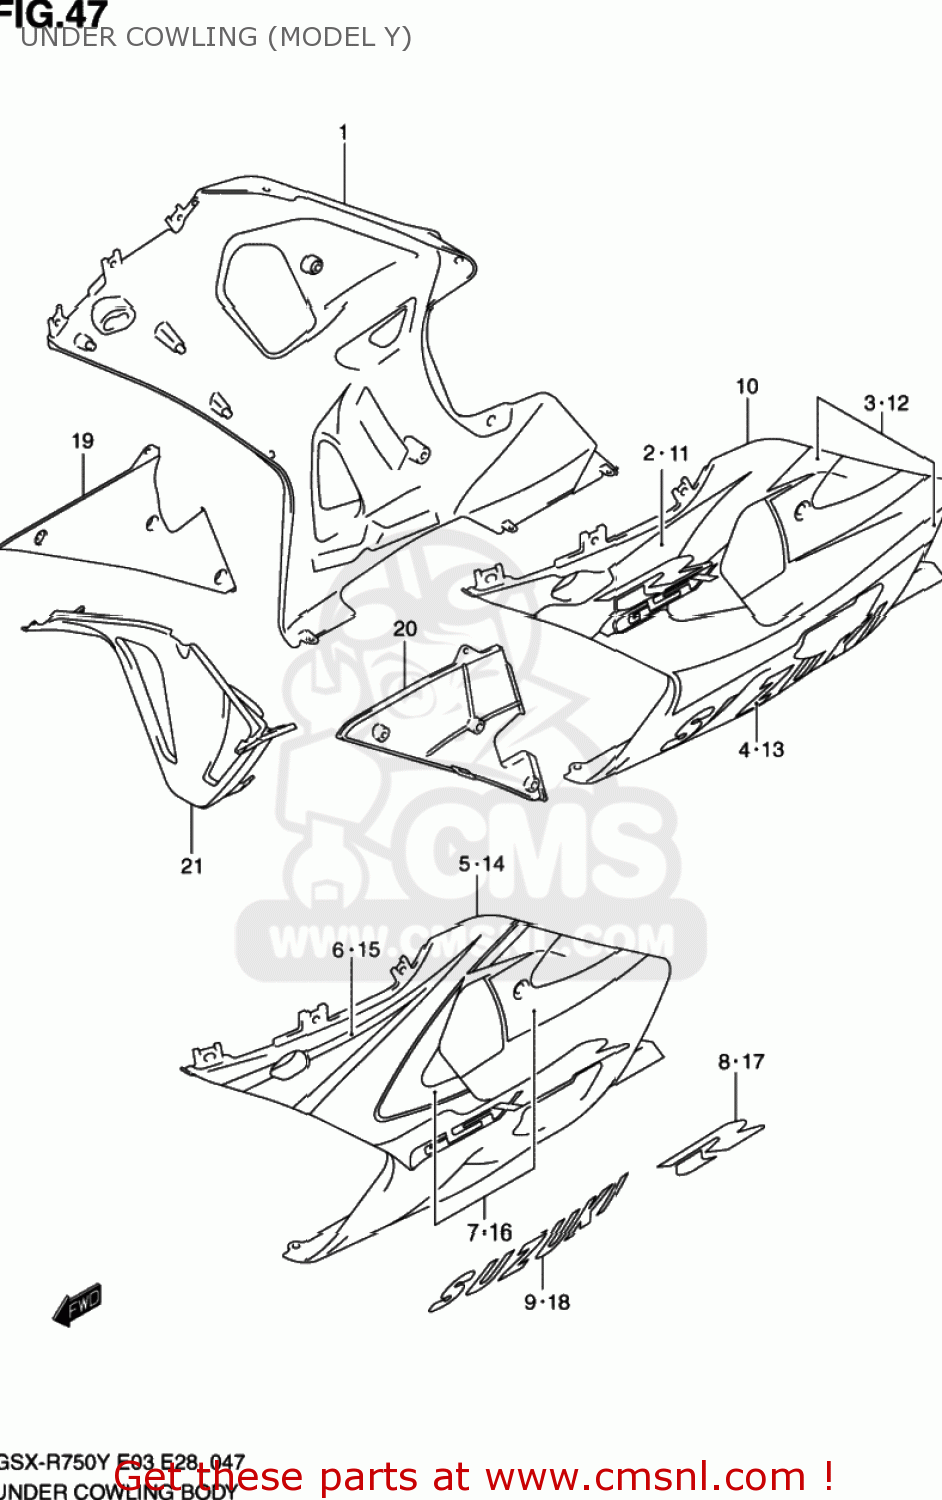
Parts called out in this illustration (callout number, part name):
1	COWLING ASSEMBLY,UNDER,RIGHT
2	TAPE,COWL UNDER,R
3	TAPE,COWL UNDER LWR,R
4	EMBLEM,COWLING UNDER,R
5	COWLING ASSEMBLY,UNDER,RIGHT
6	TAPE,COWL UNDER UPR,R
7	TAPE SET,COWL UNDER SIDE,R
8	EMBLEM,COWLING UNDER,R,R
9	EMBLEM,SUZUKI
10	COWLING ASSEMBLY,UNDER,LEFT
11	TAPE,COWL UNDER,L
12	TAPE,COWL UNDER LWR,L
13	EMBLEM,COWLING UNDER,L
14	COWLING ASSEMBLY,UNDER,LEFT
15	TAPE,COWL UNDER UPR,L
16	TAPE SET,COWL UNDER SIDE,L
17	EMBLEM,COWLING UNDER,R,L
18	EMBLEM,SUZUKI
19	COWLING,UNDER INNER,R
20	COWLING,UNDER INNER,L
21	COWLING,UNDER CTR
